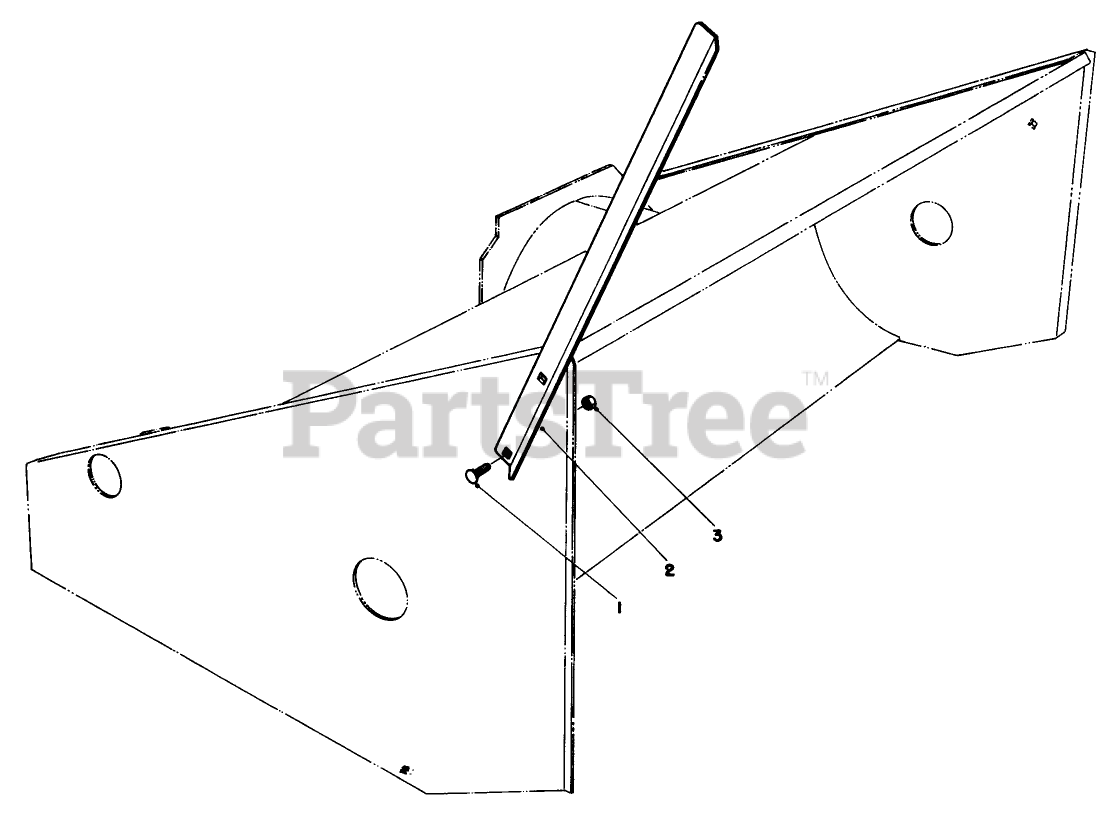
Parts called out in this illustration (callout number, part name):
1	STEP BOLT
2	Drift Cutter
3	Hex Nut
